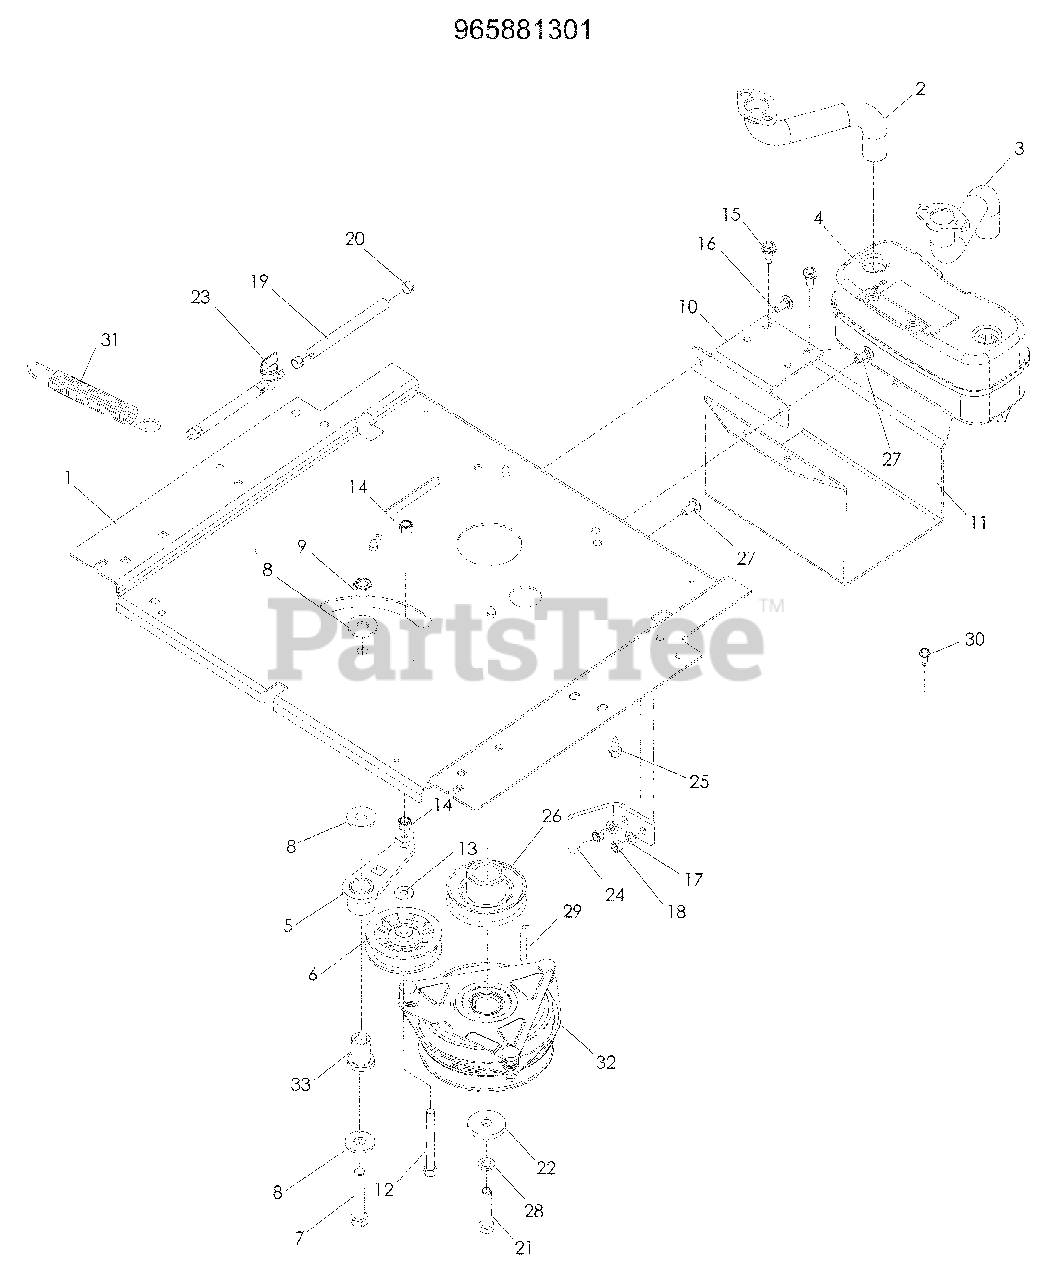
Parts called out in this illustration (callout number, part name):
1	PLATE, ENGINE
2	EXHAUST TUBE, RT
3	EXHAUST TUBE, LT
4	MUFFLER ASM TWIN
5	IDLER ARM WLDMT
6	PULLEY, IDLER
7	HCS ½-13 x 2¾
8	WASHER ½ FLAT
9	NUT ½ HEX NYLOC
10	BRACKET, MUFFLER
11	GUARD, MUFFLER
12	HCS 3/8-16 x 3½ TPBLT
13	WASHER 5/16 STD FLAT
14	NUT 3/8-16 HEX NYLOC
15	BOLT 5/16-18 x ¾ THD FRM
16	RHSNB 5/16-18 x ¾
17	WASHER 5/16 SAE FLAT
18	NUT 5/16-18 HEX NYLOC
19	FUEL LINE 5"
20	CLAMP, HOSE
21	HCS 7/16-20 x 2 GR8
22	WASHER, HEAVY
23	VALVE, FUEL
24	STOP, CLUTCH
25	HHFS 3/8-16 x 1 THD FRM
26	PULLEY, DRIVE
27	RHSNB 5/16-18 x 1
28	WASHER 5/16 SLW
29	KEY ¼ SQ x 2
30	SCREW ¼-20 x 5/8 SLF TAP
31	SPRING, DECK DRIVE
32	CLUTCH, 150 FT/LBS
33	PIVOT, IDLER
